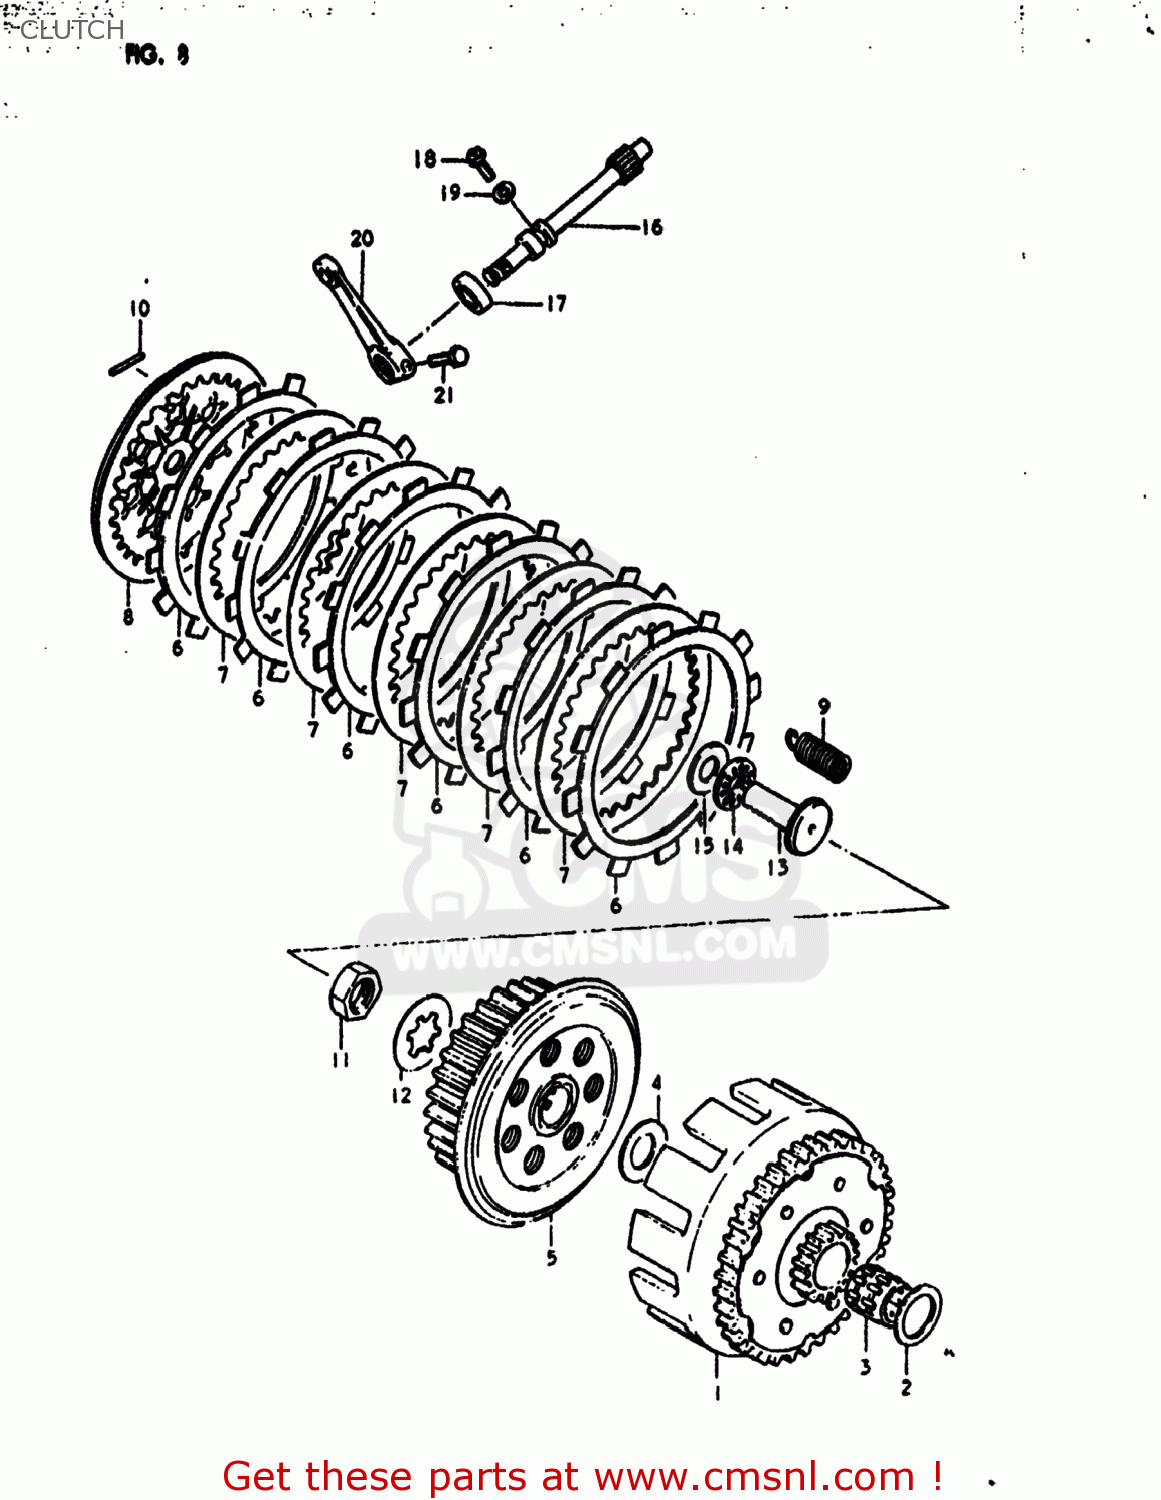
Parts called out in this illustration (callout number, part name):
1	GEAR ASSEMBLY,PRIMARY DRIVE
2	WASHER
3	BEARING(20X25X26)
4	WASHER
5	HUB,CLUTCH SLEEVE
6	PLATE,CLUTCH DRIVE
7	PLATE,CLUTCH DRIVEN
8	PLATE,CLUTCH PRESSURE
9	SPRING
10	PIN(2.5X19.8)
11	NUT
12	WASHER,LOCK
13	RACK,CLUTCH RELEASE
14	BEARING(10X22X2.8)
15	WASHER
16	PINION,CLUTCH RELEASE
17	SEAL,OIL (10X17X5)
18	BOLT(6X12)
19	WASHER
20	ARM,CLUTCH RELEASE
21	BOLT, UPPER
